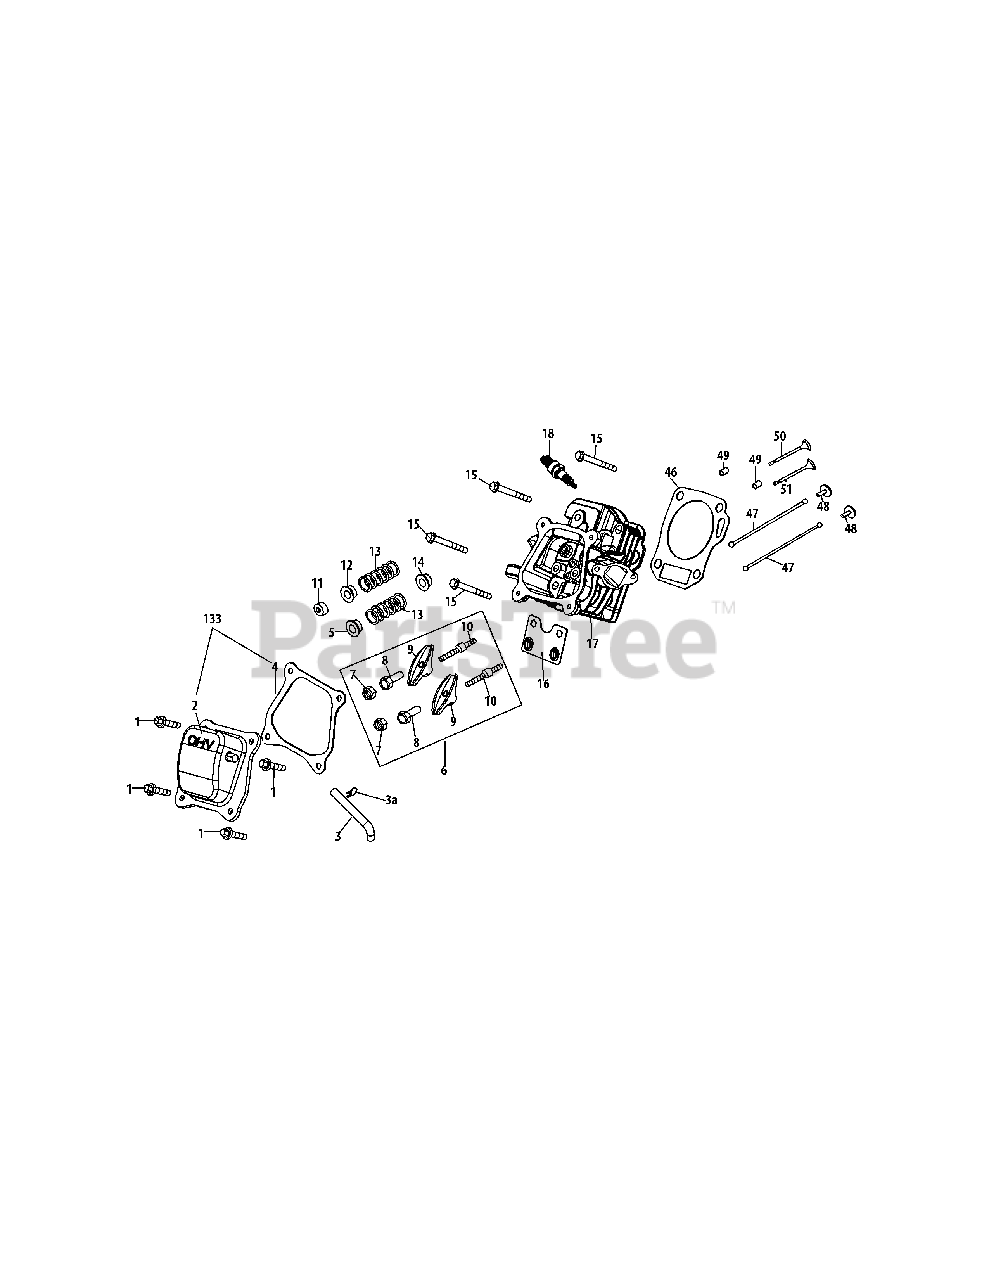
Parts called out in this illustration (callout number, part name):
2	Valve Cover
3	Breather Hose
4	Valve Cover Gasket
5	Retainer, Intake Valve Spring
6	Rocker Arm Assembly
7	Nut,Pivot Locking
8	Adjusting Nut ,Valve
11	Adjuster, Exhaust Valve
12	Retainer, Exhaust Valve Spring
13	Valve Spring
14	Intake Valve Seal
16	Push Rod Guide
17	Cylinder Head Assembly
18	Spark Plug
46	Gasket, Cylinder Head
49	Dowel Pin 10×16
50	Exhaust Valve
133	Valve Cover Kit
